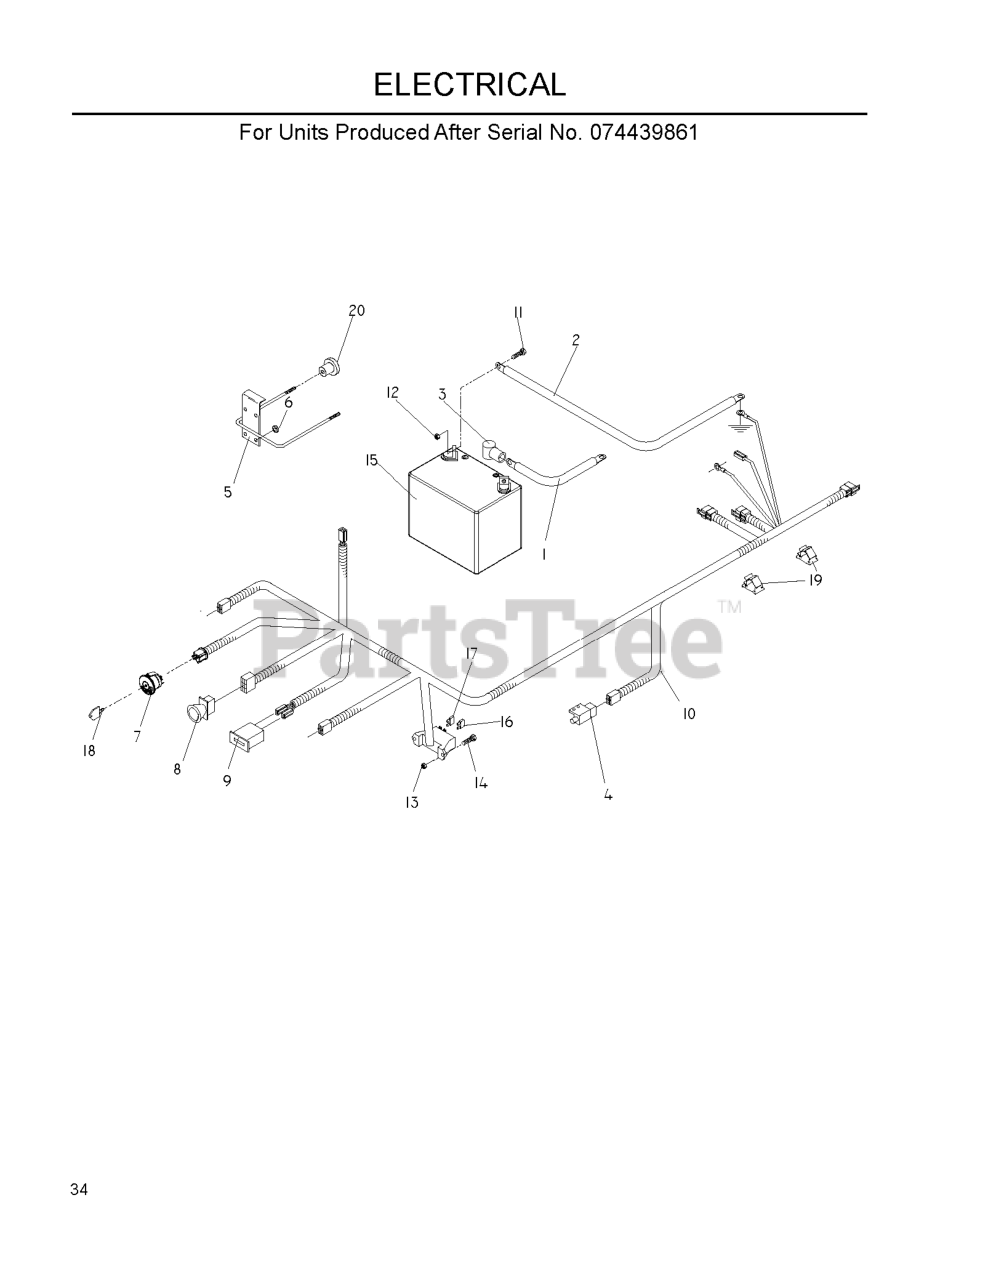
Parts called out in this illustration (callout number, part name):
1	POST.CABLE LONG
2	CABLE-NEGATIVE
4	SWITCH, BRAKE 3P
5	BATTERY HOLD DOWN
6	GROMMET, BUMPER
7	RP IGNITION SWITCH
8	RP SWITCH.PTO.TERMINAL.STD.RED
9	HOUR METER
10	HARNESS, WIRING LZ/IZ
11	HCS 5/16C X 3/4
12	NUT 5/16 NYLOC
13	NUT 10-24 NYLOC
14	SCREW, #1--24 X 1/2 SLOTTED
15	BATTERY, 12 V 330 AMP
16	FUSE, 7.5 AMP 32 VOLT ATO
17	FUSE, 20 AMP 32 VOLT ATO
18	KEY
19	PUSH-MOUNT WIRE CLIP
